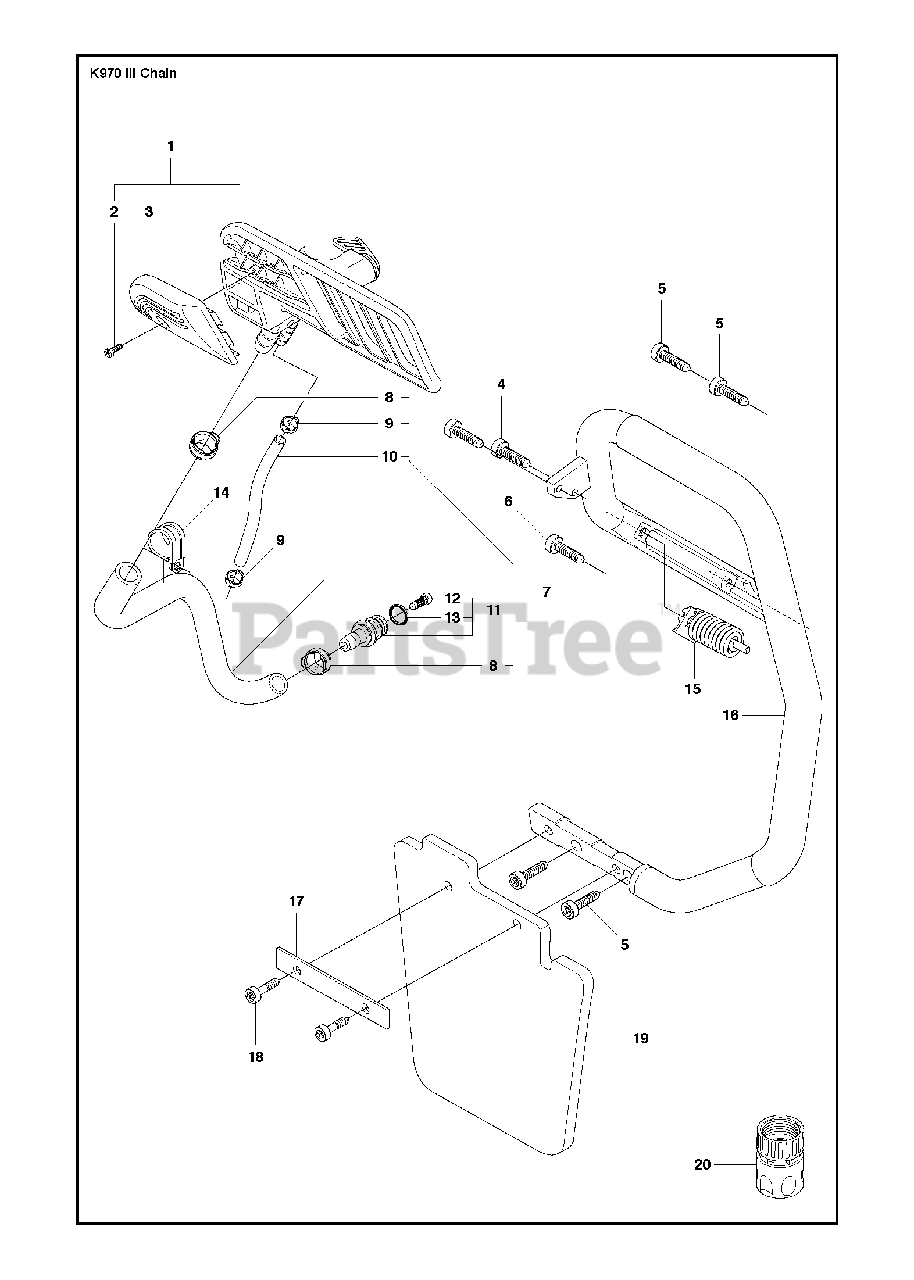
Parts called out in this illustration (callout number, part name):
2	SCREW CCRPANT
4	SCREW ITXSCT
5	SCREW ITXSCT
6	SCREW ITXSCM
8	HOSE CLAMP
11	NIPPLEIncl. 12, 13
13	O-RING
15	ANTIVIBRATION ELEMENT
18	SCREW ITXSCM
20	COUPLERUSA, Canada
